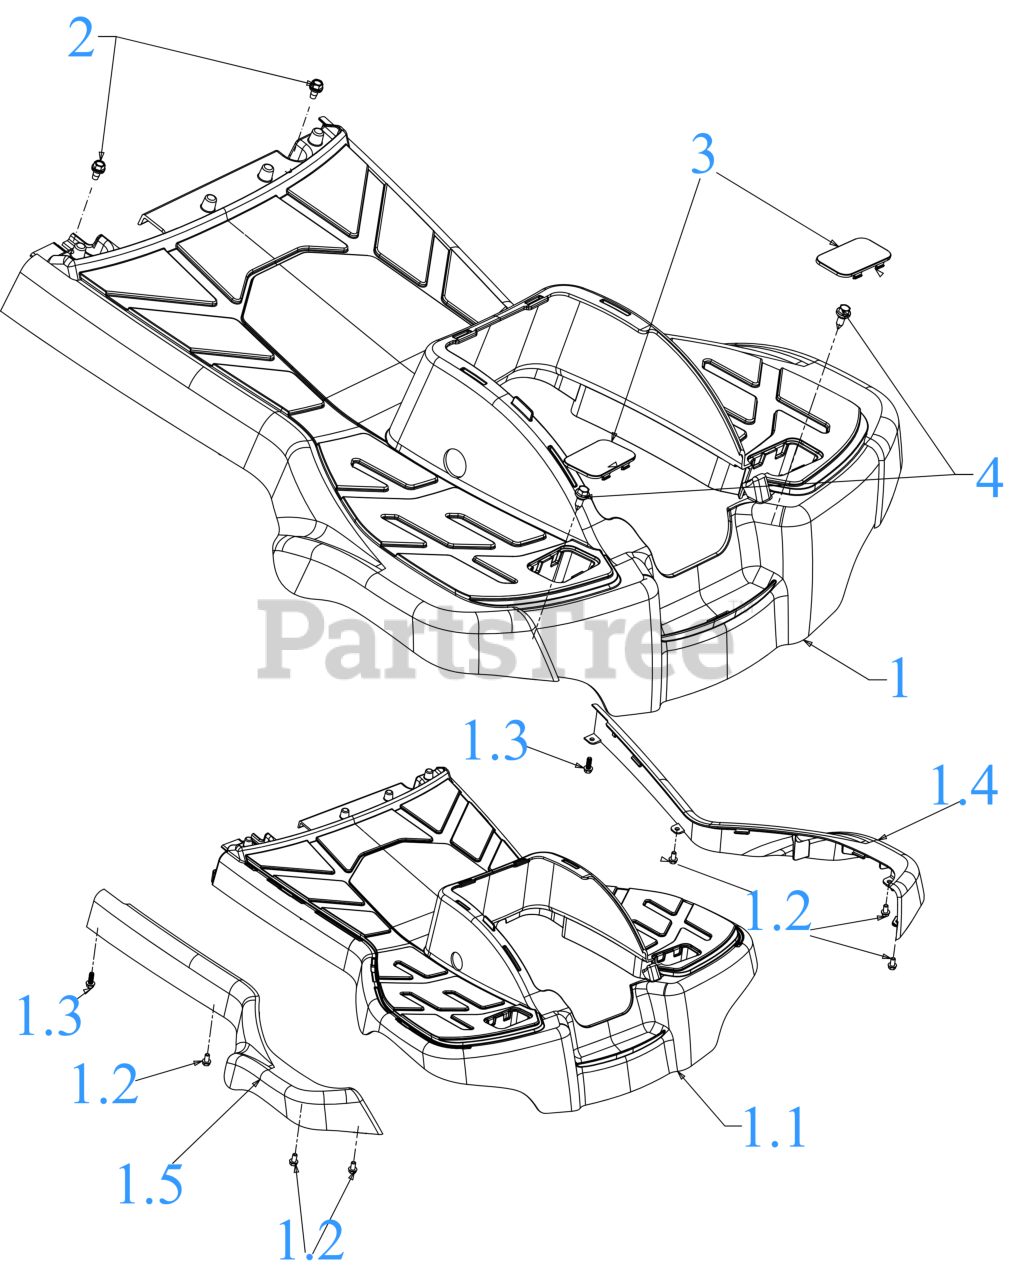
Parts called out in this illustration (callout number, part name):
1	RUNNING BOARD ASSEMBLY
1.1	RUNNING BOARD
1.2	HEX SCREW 1/4-15 x .50
1.3	SCREW 1/4-15 x .750
1.4	RUN BOARD TRIM (LH) (LIBERTY RED)
1.5	RUN BOARD TRIM (RH) (LIBERTY RED)
2	SCREW 1/4-20 x .50
3	RUNNING BOARD PLUG
4	SHOULDER SCREW
